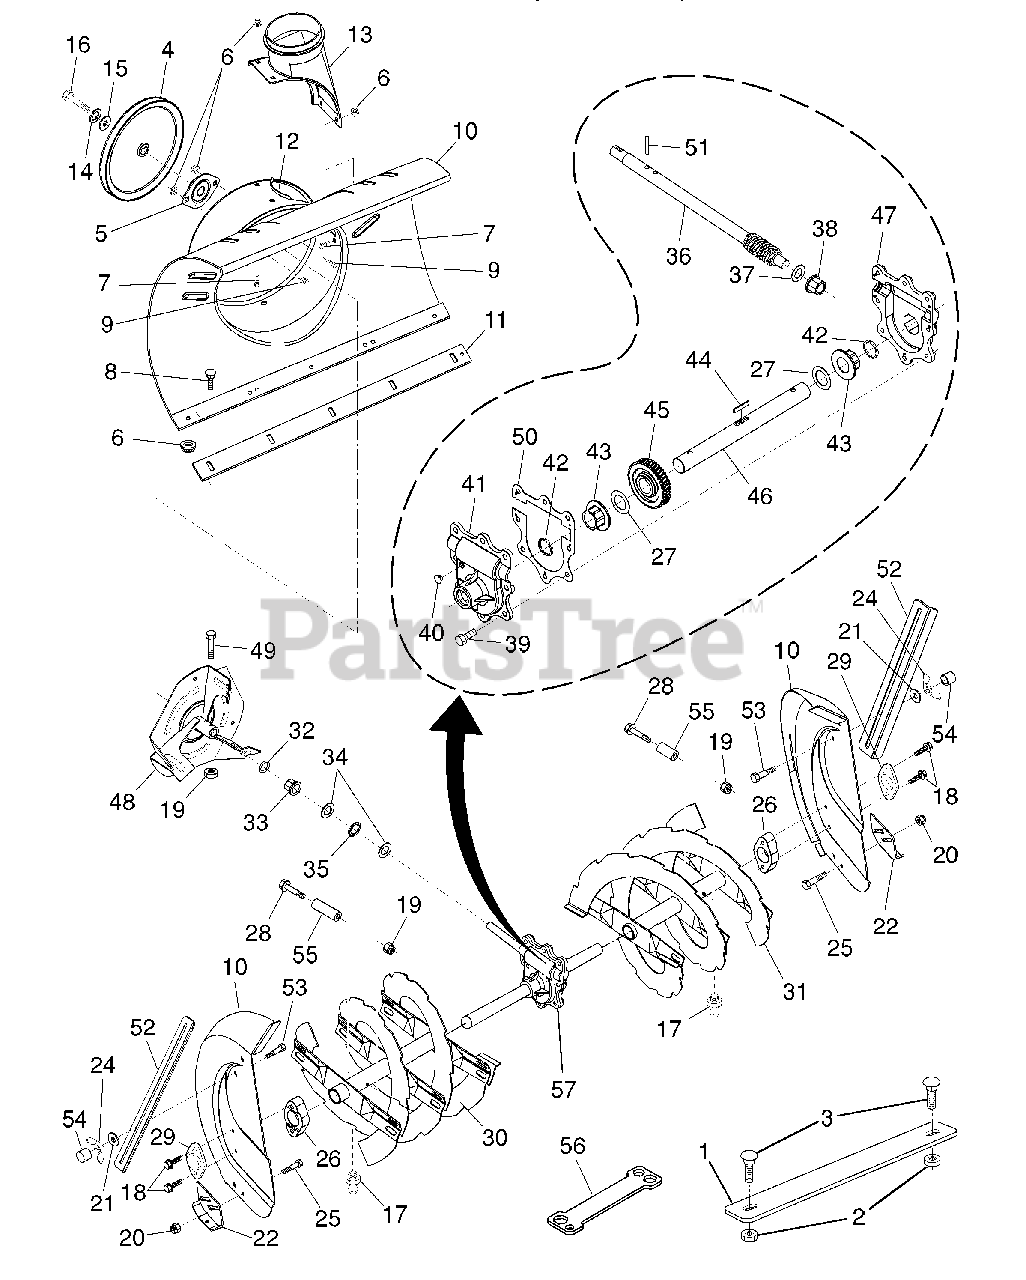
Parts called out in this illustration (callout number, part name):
1	Nut, Hex 5/16-18
2	Bolt, Carriage 5/16-18 x 1-1/4
3	Pulley, Impeller
4	Bearing Assembly, Flange
5	Nut, Hex Flange 5/16-18
6	Bolt, Flat Head, Carriage 5/16-18 x 5/8
7	Bolt, Carriage 5/16-1 8 x 5/8
8	Bolt
9	Housing, Auger
10	Bar, Scraper
11	Bracket, Corner Discharge
12	Base, Discharge Chute
13	Washer, Lock 5/16
14	Washer, Flat
15	Screw, Hex Head 5/16-18 x 3/4
16	Grease Fitting
17	Screw, Hex Head 5/16 x 1
18	Nut, Hex Lock 1/4-20
19	Nut, Hex Lock 5/16-18
20	Washer, Flat 5/16
21	Skid Plate, Heavy Duty
24	Bolt, Shoulder 1/4-20
25	Bearing Retainer, Plastic
26	Washer, Thrust, 1"
27	Bolt, Shear
28	Bearing
29	Auger Assembly, RH
30	Auger Assembly, LH
31	O-Ring
32	Bushing, Flange 3/4
33	Washer, Thrust 3/4
34	Bearing, Thrust 3/4
35	Shaft, Impeller
36	Washer, Thrust 5/8
37	Bushing, Flange 5/8
38	Screw, Hex Head 5/16-18 x 3/4
39	Plug, Case
40	Housing, Gearbox, RH
41	Seal, Oil
42	Bushing, Flange, 1"
43	Key, Square 1/4 x 1/4 x 7/8
44	Gear, Worm
45	Shaft, Auger
46	Housing, Gearbox, LH
47	Impeller Assembly
48	Screw, Hex Head 1/4-20 x 1-5/8
49	Gasket, Gearbox
50	Pin, Roll 3/16 x 1-1/8
51	Bar, Drift Cutter
52	Bolt
53	Stop
55	Multi-Wrench
56	Gearbox Assembly
57	Gearbox Assembly
